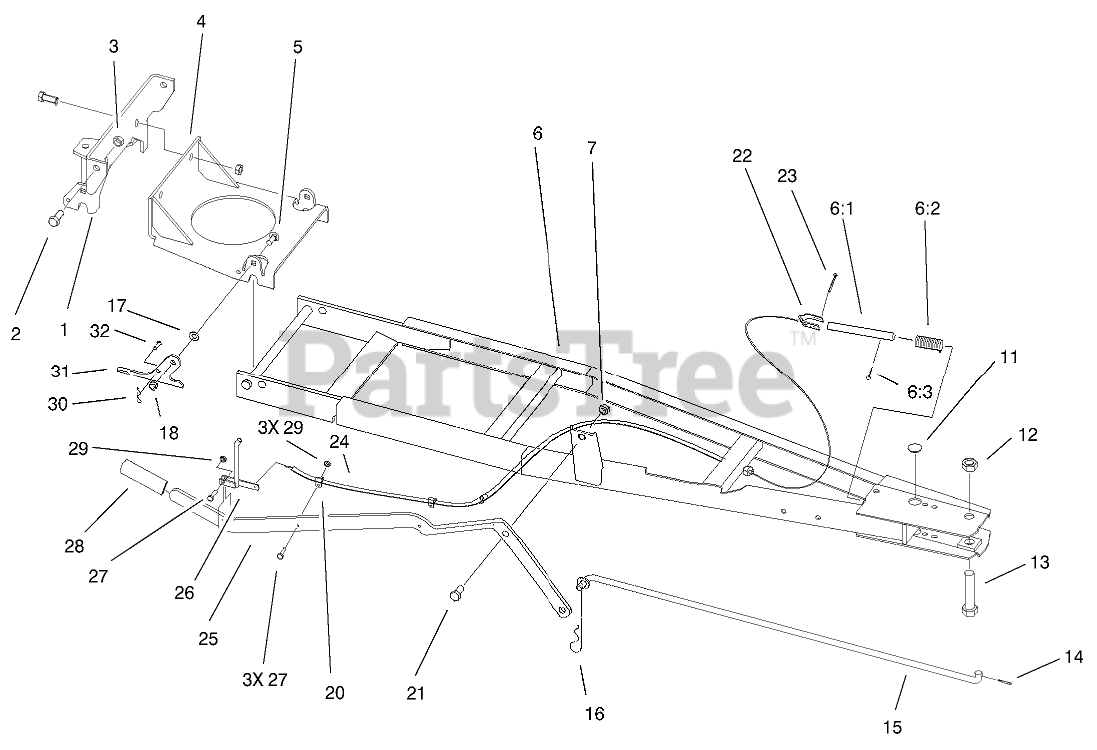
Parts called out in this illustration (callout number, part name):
1	BRACKET-MOUNTING
2	SCREW-HH
3	NUT-LOCK, NI
4	BRACKET-BLADE MOUNT
5	BOLT-CARR
6	BLADE FRAME ASM
6:1	PIN-INDEX
6:2	SPRING-COMPRESSION
6:3	PIN-COTTER
7	NUT-JAM
11	PLUG
12	NUT-LOCK
13	SCREW-HH
14	PIN-COTTER
16	PIN-HAIR
17	WASHER-FLAT
18	NUT-LOCK, NI
20	R-CLAMP
21	SCREW-HH
22	BRACKET - CABLE END
23	PIN-COTTER
24	CABLE-TENSION
25	LEVER-BLADE
26	LEVER-INDEX
27	SCREW-HH
28	GRIP
29	NUT-LOCK
30	PIN-HAIR
31	PLATE-LATCHING
32	PIN-CLEVIS
